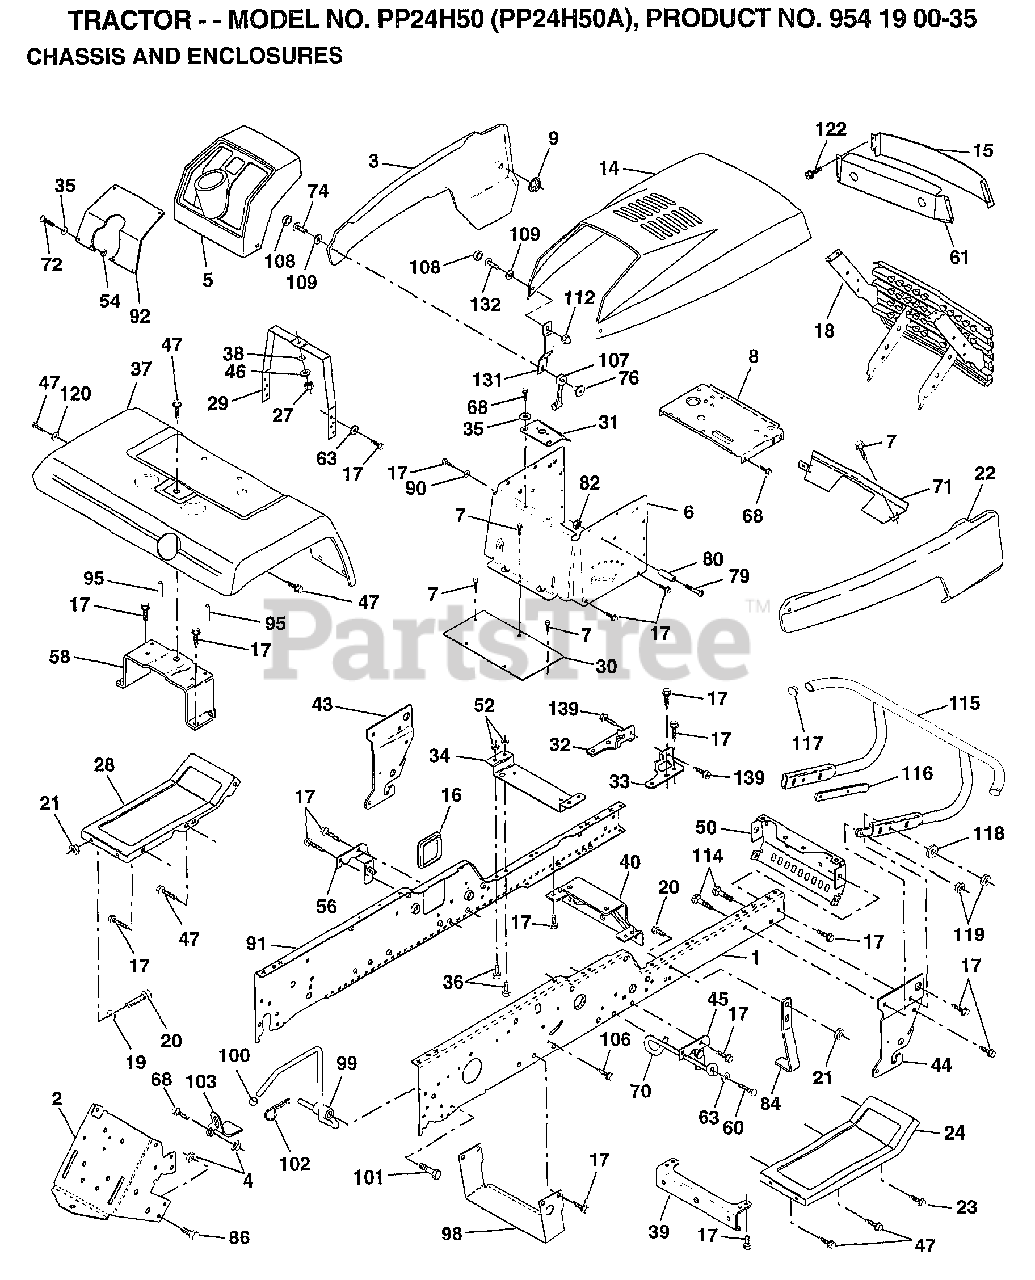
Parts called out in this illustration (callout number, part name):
1	"RAIL,FRAME RH"
2	DRAWBAR GT
3	"PANEL ASM-SIDE,LH"
4	NUT.7/16
5	DASHBOARD BLACK
6	DASH LOWER
7	SCREW
8	SUPPORT.DASH.BTRY
9	PAL NUT LT
14	"HOOD, YARD PRO"
15	LENS.BAR.CLEAR
16	COVER ACCESS
17	SCREW
19	WASHER
20	BOLT
22	"PANEL ASM SIDE,RH"
23	SCREW GTV
24	FOOTREST.RH.LT/GT
28	FOOTREST.LH.LT/GT
29	DASH.SUPT.YP/HUSQ
30	SADDLE.HYDRO.95
31	BRKT SUPT 1-PC VG
32	BKRT.PIVOT.CHASSIS.LH
33	BKRT.PIVOT.CHASSIS.RH
34	BRACKET.ENG.SUPT.
35	WASHER
36	BOLT
37	FENDER.PNT.
38	LOCKWASHER
39	BRACKET.AXLE.FRT.
40	"BRKT SUPPORT,AXLE"
43	BRACKET.SUS.FT.LH
44	BRACKET.SUS.FT.RH
45	BRACKET.SUSP.RH.
46	WASHER PM
47	SCREW LT
50	"BRKT CHASSIS,FRNT"
56	BRACKET.SUSP.LH.
58	BRKT.ASM.FENDER
59	SCREW
60	SCREW
61	BEZEL.1 PC
63	WASHER
68	SCREW LT
70	GUIDE.BELT.MID.SP
72	SCREW
74	SCREW
76	WELDNUT
79	SCREW
80	SPACER LT
84	STOP.OVER.CENTER
86	BOLT
90	LOCKWASHER
91	"RAIL FRAME,LH"
95	NUT-PUSH YT
98	BRACKET SKID CHAS
99	ROD BYPASS
101	SCREW LT
102	RETAINER M
103	LOCK BYPASS BRKT
107	HOOD LATCH T
108	SNAP CAP LT
109	WASHER LT
112	ACORN NUT RB
114	BOLT.3/8-14X1.25
115	BUMPER.ASM
116	BRACKET.EXT.BUMP.
117	PLUG.PLASTIC
118	WASHER
120	WASHER HYT
122	SCREW.HEX.WS.HD
131	BKT.SPT.HOOD/PANL
132	SCREW.10-24X3/8.
139	BOLT.SHOULDER.5/16-18
